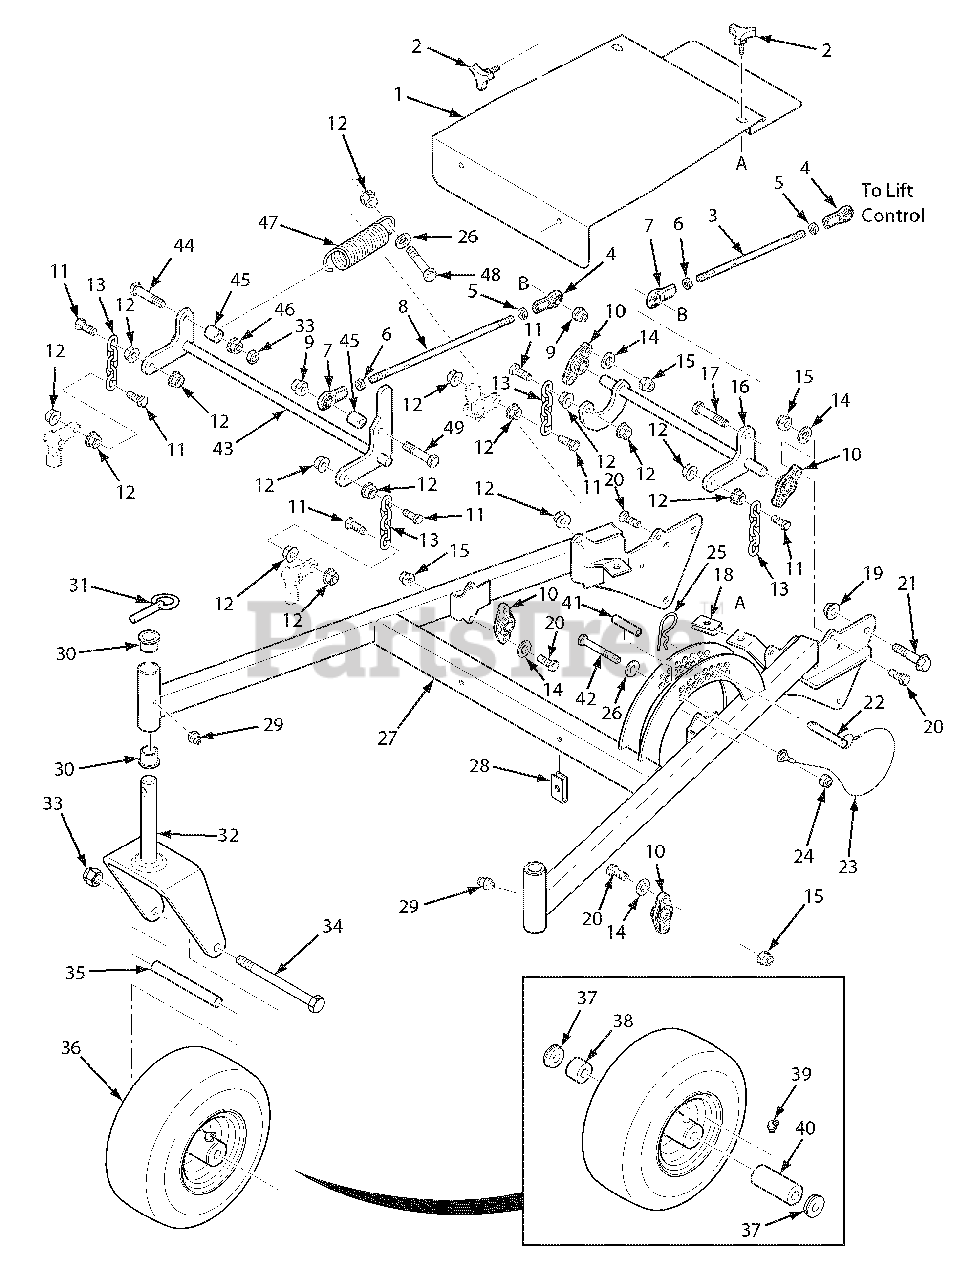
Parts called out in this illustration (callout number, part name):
1	Belt Cover, 48V/52V
2	Knob w/Stud
3	Linkage Assembly, Deck Lift
4	Rod End, 1/2-20 LH
5	Nut, 1/2-20 UNF LH Jam
6	Nut, 1/2-20 RH
7	Rod End, 1/2-20 RH
8	Linkage Assembly, Deck Lift
9	Nut, Elastic Stop 1/2-13
10	Bearing
11	Bolt, Hex Head 3/8-16 x 1-1/2"
12	N ut, Serrated Flange 3/8-16
13	Chain
14	Flatwasher, 5/16-.375 x .875 x .083
15	Nut, Elastic Stop 5/16-18
16	Rear Deck Lift Weldment
17	Bolt, Hex Head 1/2-13 x 2-1/2"
18	U-Nut, 3/8-16
19	Nut, Spiral Lock 1/2-13
20	Bolt, Hex Head 5/16-18 x 1-1/4"
21	Capscrew, Serrated Flange 1/2-13 x 1"
22	Ring Pin Assembly
23	Lanyard
24	Nut, Elastic Stop 3/8-16
25	Hair Pin Cotter, .177 x 3-1/4"
26	Flatwasher, 3/8-.391 x .938 x .105
27	Frame Weldment, 52V
28	U-Nut, 3/8-16
29	Grease Fitting
30	Bushing, 1.003 I.D.
31	Quick Pin
32	Caster Wheel Yoke
33	Nut, Elastic Stop 1/2-13
34	Bolt, Hex Head 1/2-13 x 6-1/2"
35	Sleeve, Caster Wheel
36	Caster Wheel Assembly
37	Bearing, Oilite
38	Roller Bearing
39	Grease Fitting
40	Roller Bearing
41	Spacer
42	Bolt, Hex Head 3/8-16 x 2-3/4"
43	Front Deck Lift Weldment
44	Bolt, Hex Head 1/2-13 x 3"
45	Spacer
46	N ut, Serrated Flange 1/2-13
47	Spring Deck Lift
48	Bolt, Hex Head 3/8-16 x 1-1/2" Grade 8
49	Bolt, Hex Head 1/2-13 x 2-3/4"
